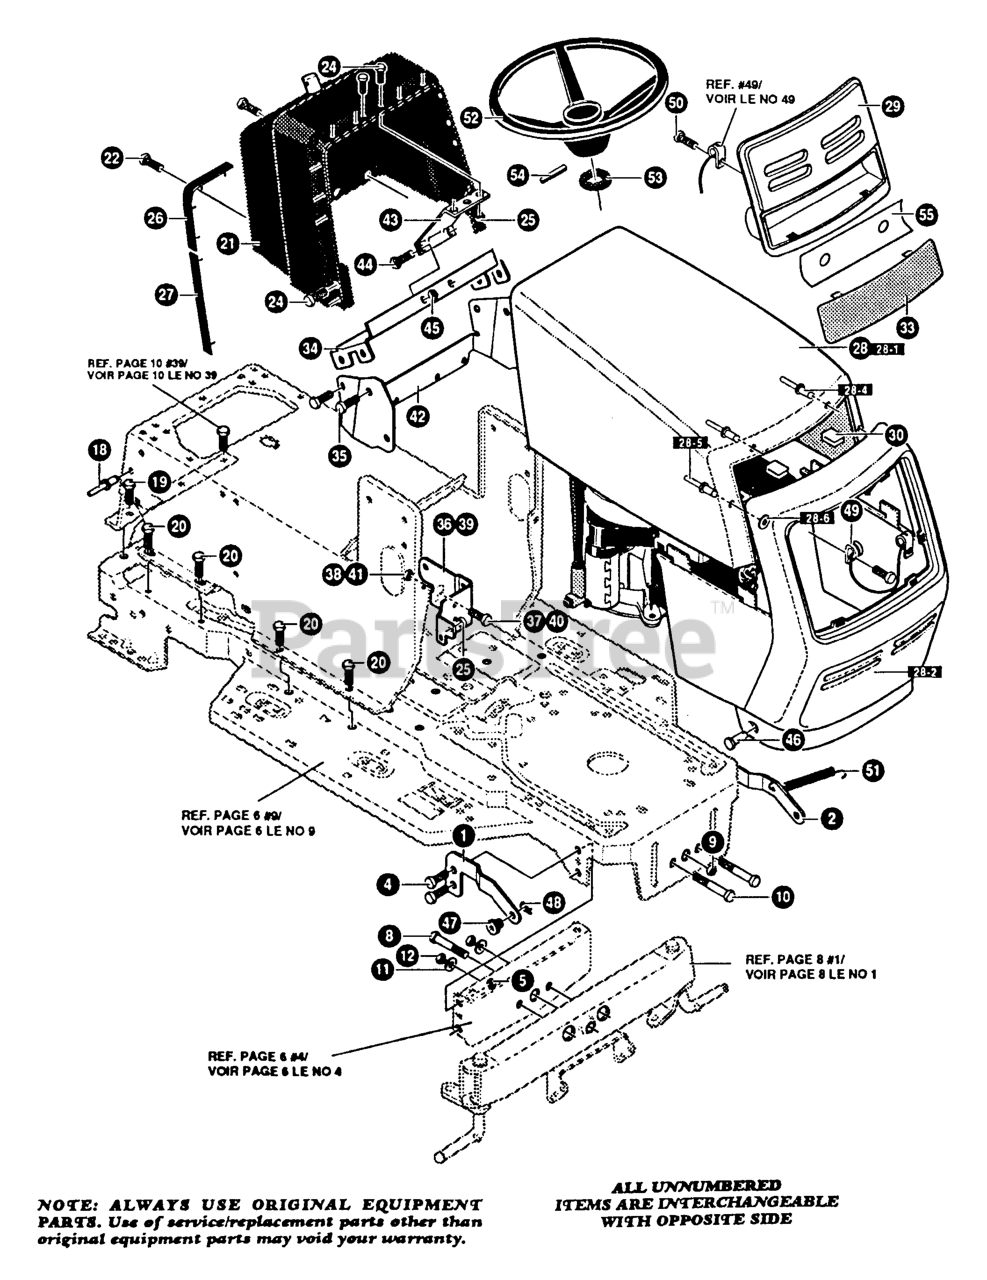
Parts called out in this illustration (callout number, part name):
1	BRACKET, RH
2	BRACKET, LH
4	SCREW
11	WASHER
12	NUT
18	RIVET
19	SCREW
26	BUMPER
27	BUMPER
28-1	KIT HOOD
28-2	KIT HOOD
28-6	WASHER
29	INSERT
36	BRACKET, RH
39	BRACKET, LH
47	BEARING HOOD
49	LANYARD, HOOD
50	SCREW
52	STEERING WHEEL
53	SPACER
55	FOIL, LENS
